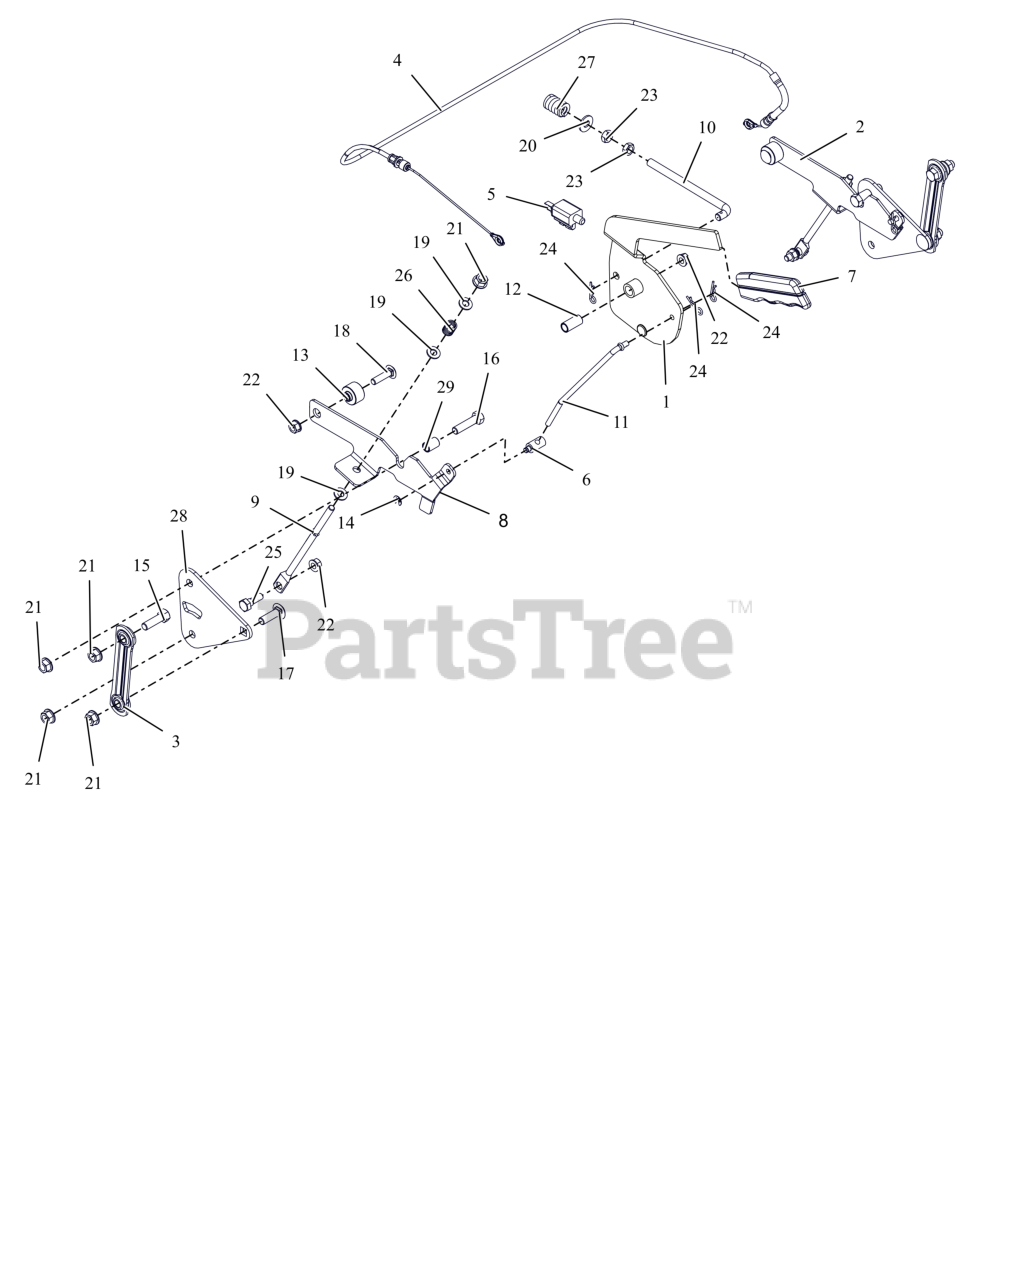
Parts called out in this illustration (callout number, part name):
1	LEVER, PARKING BRAKE
2	ARM, BRAKE - LH (W/PIN)
3	LINK, STAMPED STEERING
4	CABLE, BRAKE - PARKING
5	SWITCH, SINGLE POLE N.O.
6	TRUNION, 1/4-20
7	GRIP, PARKING BRAKE (YELLOW)
8	ARM, BRAKE - RH
9	ROD, LINK - TRANSMISSION BRAKE
10	ROD, OVER CENTER
11	ROD, BRAKE LINK
12	BSHG-SLV .385X.500X1.045
13	SPCR, FLANGE
14	RG-RTNG-EXT .250X.025
15	BLT, HEX .38-16X1.25 G5 ZCC
16	BLT, HEX .38-16X1.50 G5 ZCC
17	BLT,RHSSN .38-16X1.25 G5 ZCC
18	BTL,RHSSN .313-18 X 1.25 G5 ZCC
19	WSHR,FLT .344X.688X.065 ZCC
20	WSHR,FLT .375X.875X.083 ZCC
21	NUT-LK-TOP-FLG .38-16 ZC120
22	NUT-LK-TOP-FLG .312-18 GF ZCC
23	NUT-JAM .375-16 G2 ZCC
24	PIN, HAIR #213 .08X1.19 ZCC
25	BOLT,SHLDR .38X.25 -.31-18X.75
26	SPRING, COMPRESSION
27	SG-COMP .187X.56X1.62
28	PLATE, TRANSAXLE (BLACK)
29	SPCR SLEEVED .385X.500X.718
